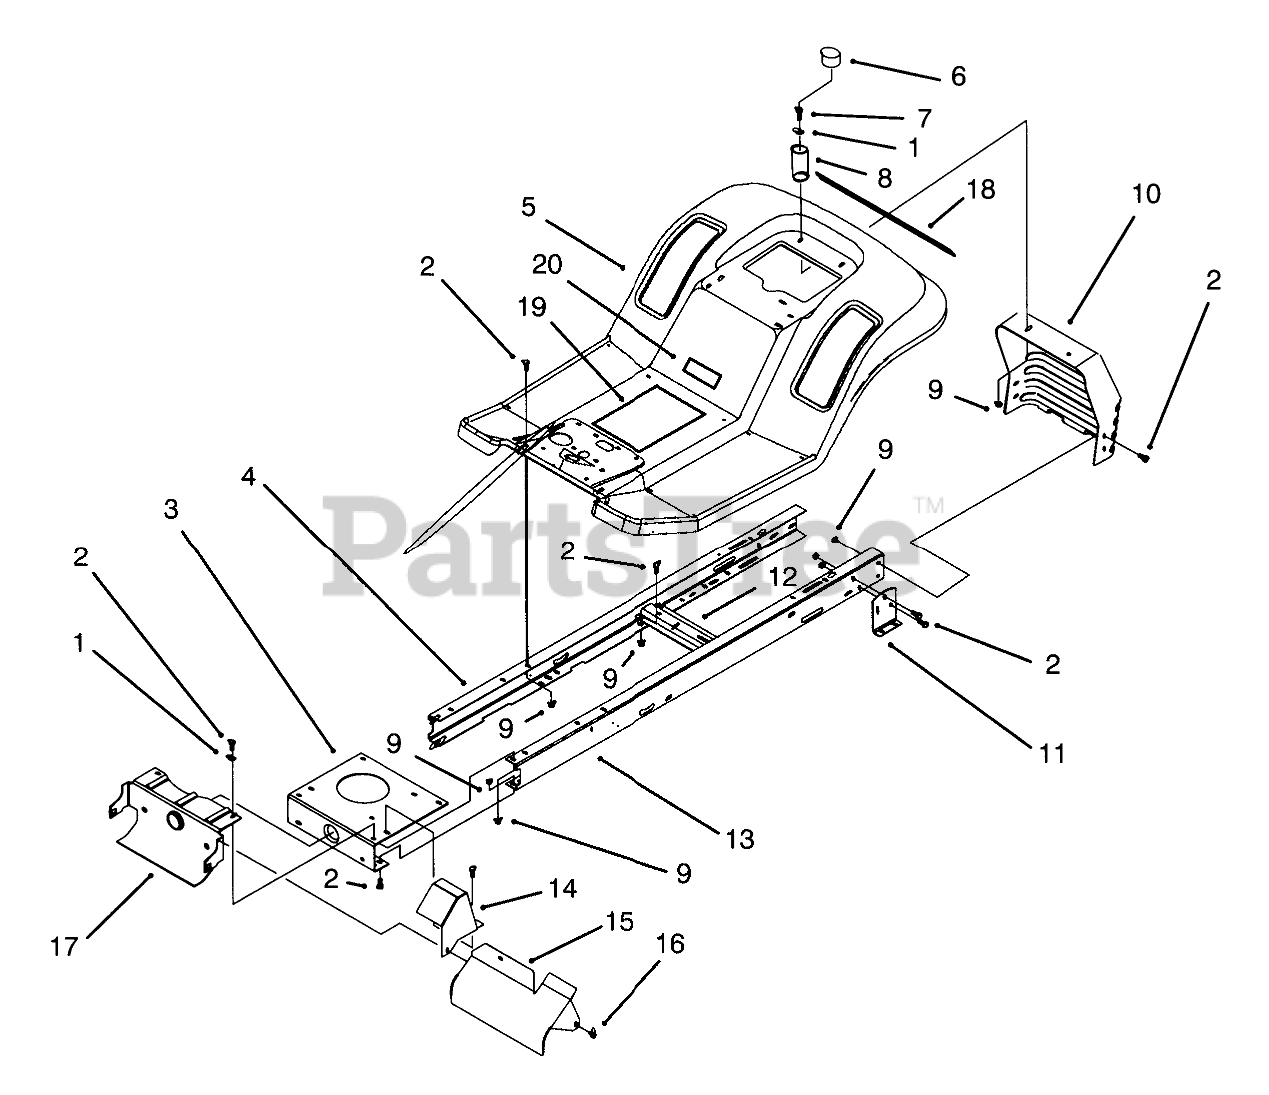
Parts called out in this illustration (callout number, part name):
1	WASHER-PLAIN
2	SCREW-HH
3	Plate-Engine Mount
4	Frame-Rail R.H.
5	BODY-REAR
6	CAP-PROTECTOR
7	SCREW-HH
8	SPRING-COMPRESSION
9	NUT-LOCK, NI
10	Panel-Rear Hitch
11	Bracket-Transaxle
12	Bracket-Idle Pivot
13	Frame-Rail L.H.
14	Shield-Exhaust Pipe
15	Shield-Muffler
16	SCREW-HWHTF
17	Support-FrontAxle
18	DECAL - REAR BODY
19	Decal-Instruction
20	Decal-Made In USA
